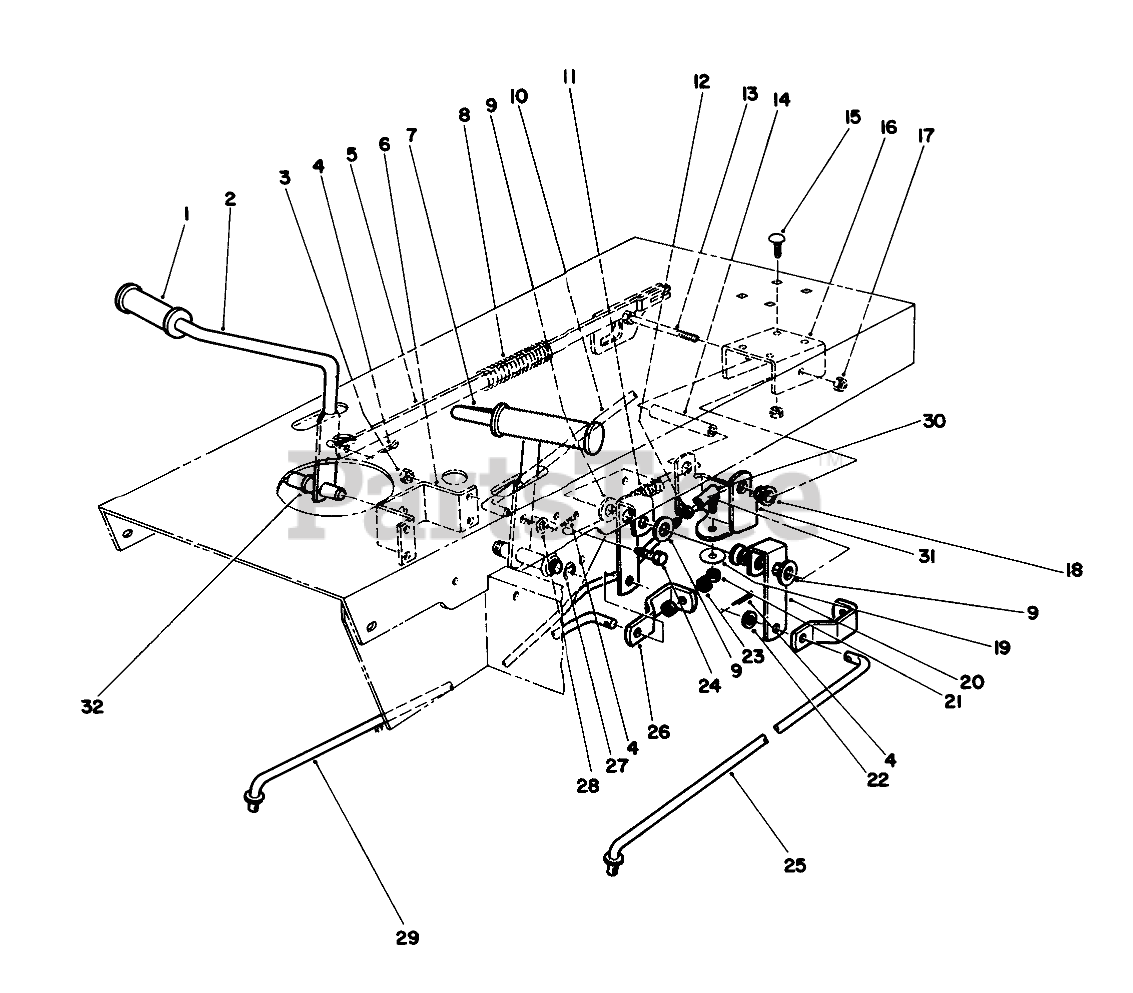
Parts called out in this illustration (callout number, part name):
1	FOOT PAD
2	BRAKE PEDAL WA B
3	NUT-LOCK, NI
4	PIN-COTTER
5	BRAKE LINK WA B
6	FOOT PEDAL BRACKET
7	CLUTCH PEDAL WA B
8	EXTENSION SPRING
9	WASHER-FLAT
10	CLUTCH ROD
11	SPRING-EXTENSION
12	NUT-JAM
13	SCREW-HH
14	CLUTCH BRACKET SLEEVE
15	SCREW-CARR
16	CLUTCH SUPPORT BRKT B
17	NUT-LOCK, NI
18	BUSHING
19	WASHER-PIVOT
20	STEERING LEVER
21	NUT-LOCK, NI
22	WASHER-PLAIN
23	NUT-JAM
24	SCREW-HH
25	LEFT FRONT ROD
26	PULL ROD LINK
27	E-RING
28	WASHER-FLAT
29	RIGHT FRONT ROD
30	BALLJOINT-RH (W/GROMMET)
31	CLUTCH BRACKET
32	Nyliner
